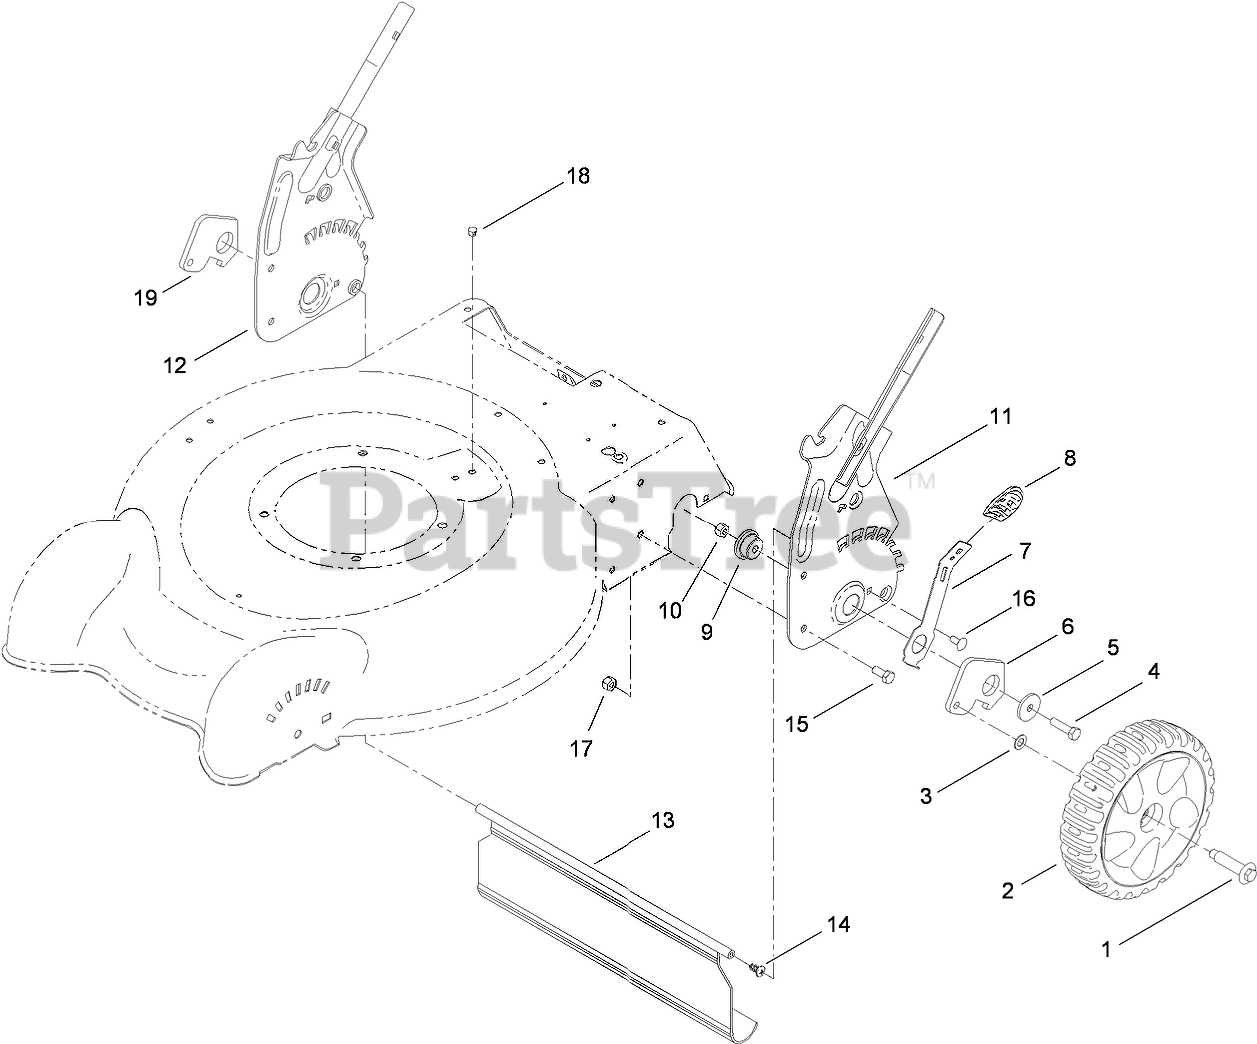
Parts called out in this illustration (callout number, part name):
1	BOLT-SHOULDER
2	8 INCH WHEEL AND TIRE ASM
3	WASHER
4	SCREW-HH
5	Washer-Flat
6	Arm-Pivot, Rear (LH)
7	Arm-Spring
8	Knob-Lever, HOC
9	Bushing-Mount, HOC
10	NUT-LOCK, NI
13	SHIELD-TRAILING
14	SCREW-PTH
15	SCREW-HH
16	SCREW-CARR
17	NUT-LOCK, NI
18	Plug-Dome
19	ARM-PIVOT, REAR (RH)
